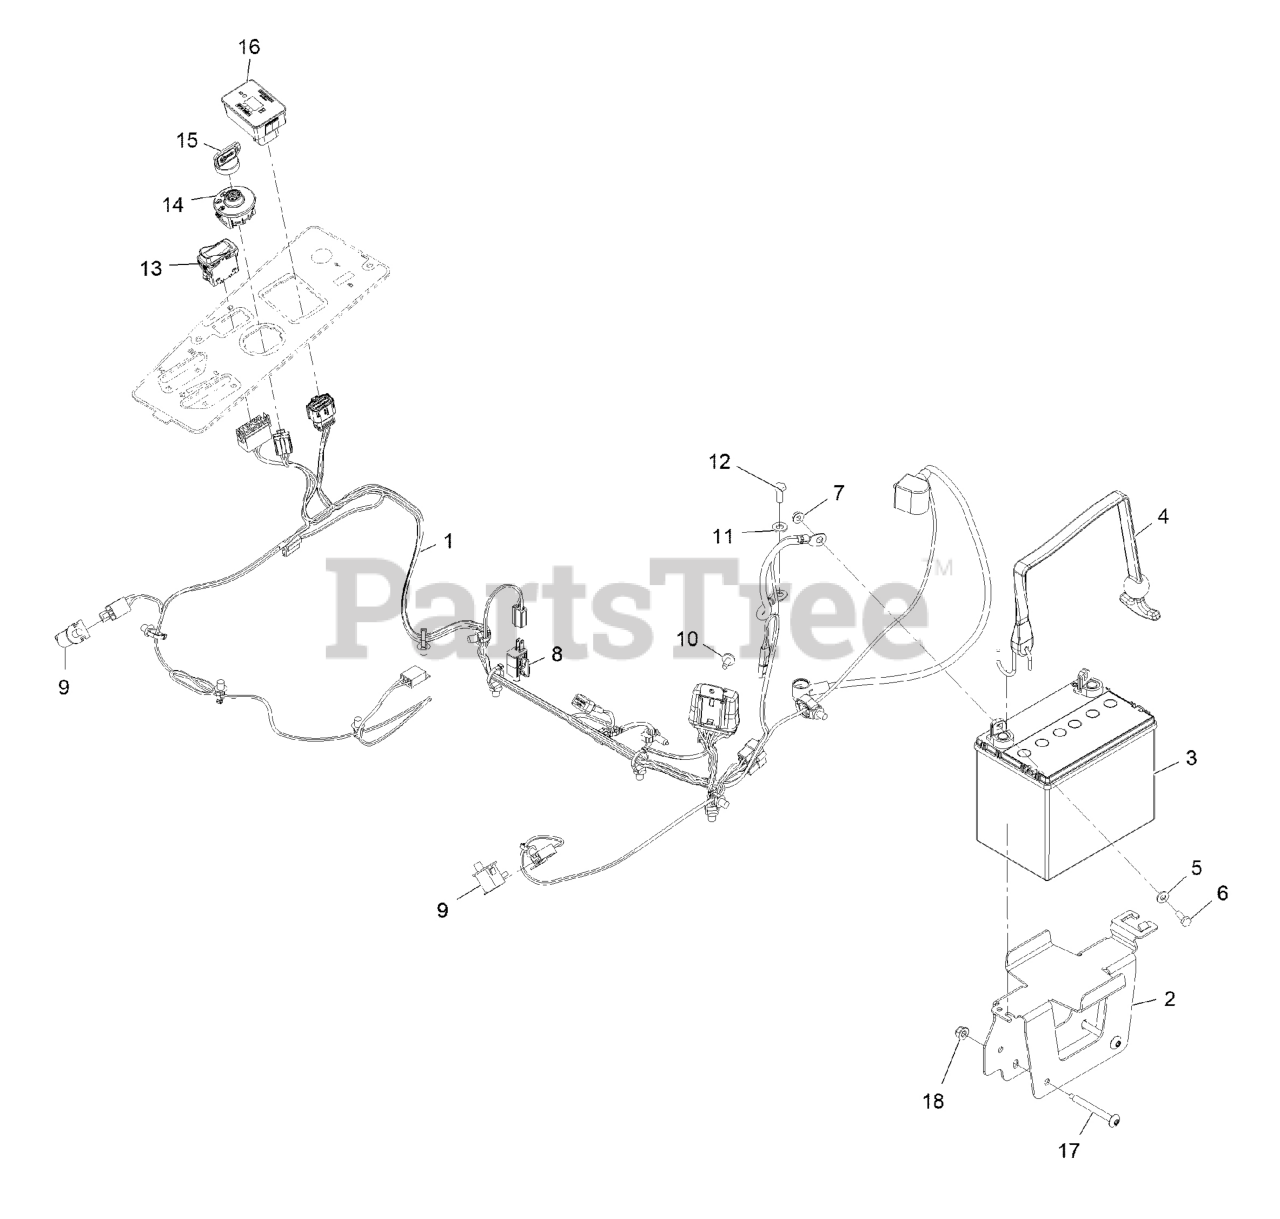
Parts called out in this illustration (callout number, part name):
1	Harness-Wire
2	TRAY-BATTERY
3	Battery
4	STRAP, BUNGEE
5	WASHER-FLAT
6	SCREW-HH
9	SWITCH-BAIL
10	SCREW-TORX
11	WASHER-PLAIN
12	SCREW-HH
13	SWITCH-ROCKER, ON-NONE-ON
14	SWITCH-IGNITION
15	KEYS-IGNITION (SPARE PAIR
15	KEY-IGNITION
16	MODULE ASM
17	SCREW-TORX
18	NUT-HF, NI
